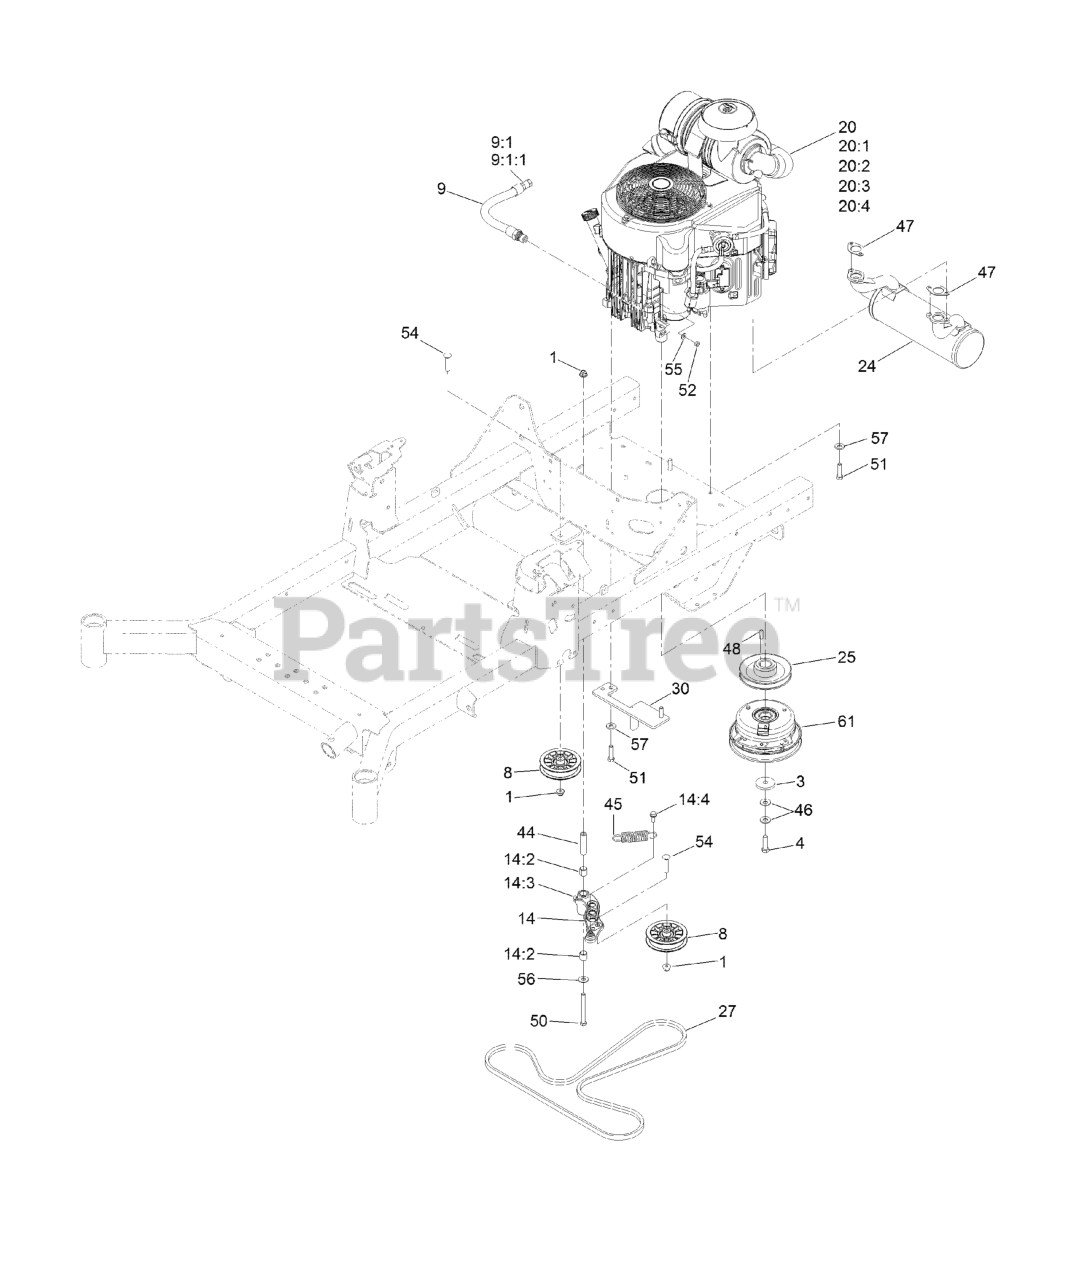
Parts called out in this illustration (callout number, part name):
1	NUT-HF, NI
3	WASHER-CLUTCH
4	SCREW-HH 7/16-20 X 1 1/2 W/LOCTITE
8	PULLEY-FLAT IDLER
9	ENGINE OIL DRAIN HOSE ASM
9:1	PLUG-HH
9:1:1	O-RING
14	IDLER ARM ASM
14:2	SLEEVE-BEARING
14:3	FITTING-GREASE, 90 DEG
14:4	SCREW-THD ROLL, HWH
20:1	Kawasaki 49065-7007 Engine Oil Filter
20:2	Kawasaki 49065-7007 Engine Oil Filter
20:3	Kawasaki 11013-7045 Safety Filter
20:4	Kawasaki 11013-7044 Engine Air Filter
24	MUFFLER
25	SHEAVE (W/HUB)
27	BELT-V
30	ANCHOR-CLUTCH
44	BUSHING-PIVOT, IDLER
45	SPRING-EXTENSION
46	WASHER-SPRING
47	GASKET-EXHAUST
50	SCREW-HH
51	SCREW-HH
52	NUT-HEX
54	SCREW-CARR
55	WASHER-FLAT
56	WASHER-FLAT
57	WASHER-BELLEVILLE
